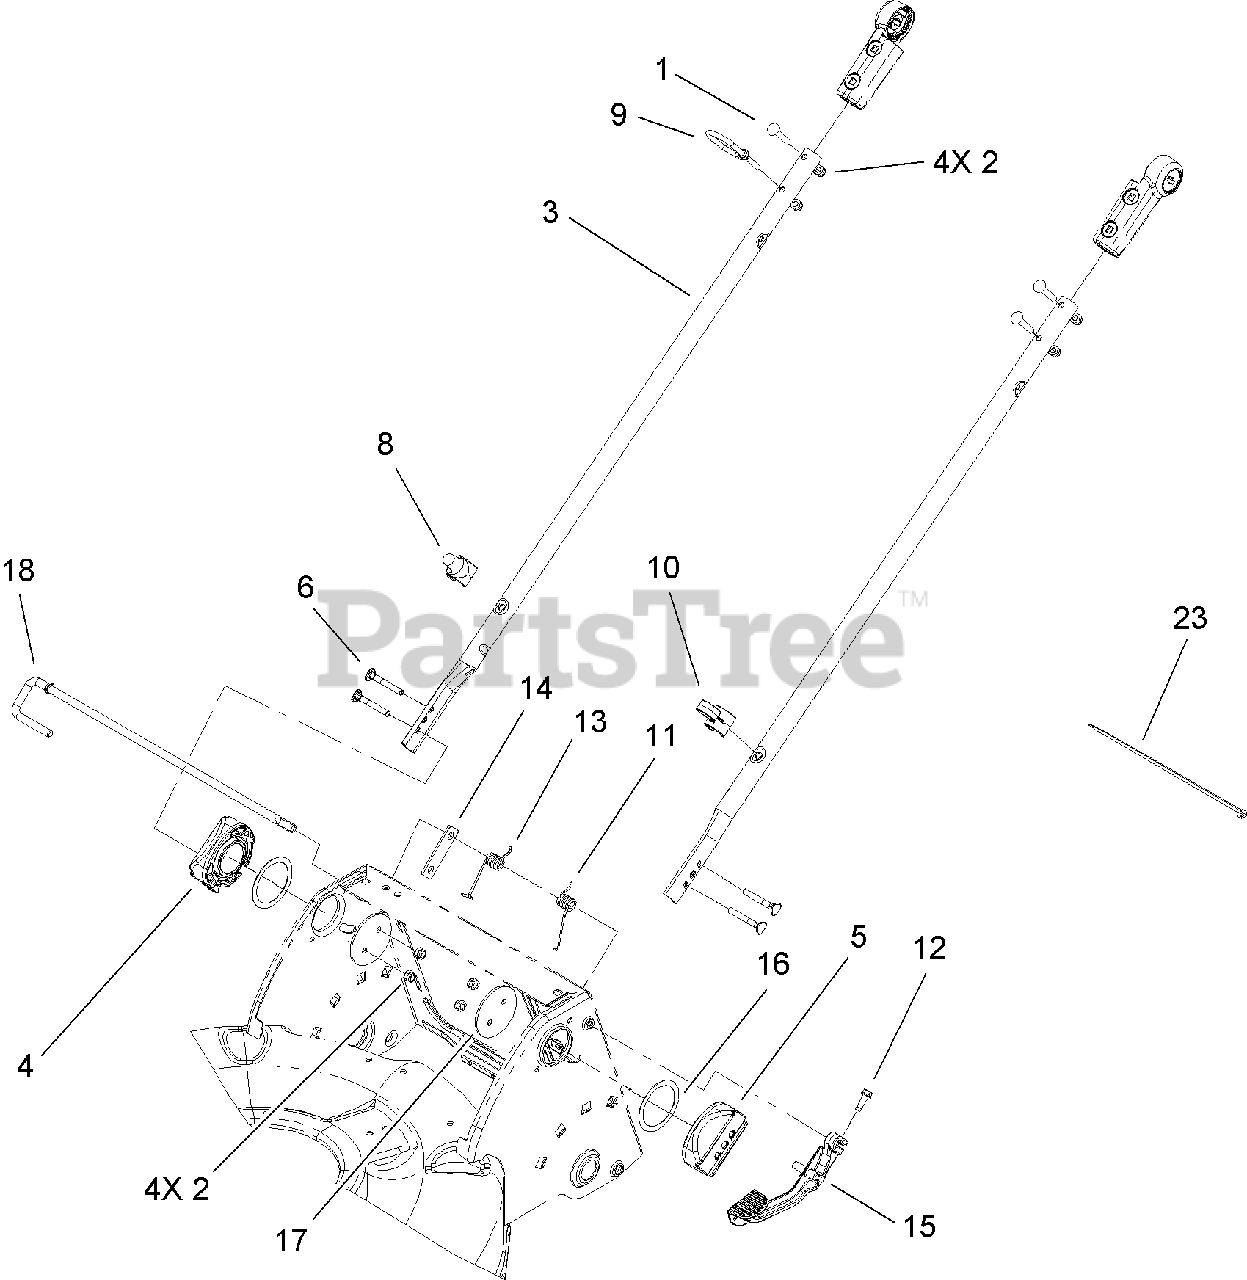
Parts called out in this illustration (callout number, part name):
1	SCREW-CARR
2	NUT-LOCK, NI
4	MOUNT-HANDLE, RH
5	MOUNT-HANDLE, LH
8	GUIDE-ROPE, LOWER
9	GUIDE-ROPE, UPPER
10	Guide-Cable
11	SPRING-TORSION, LH
12	SCREW-HWHTF
13	SPRING-TORSION, RH
14	PLATE-LOCK, HANDLE
15	LEVER-RELEASE
16	WASHER-NYLON
18	ROD-HANDLE RELEASE
23	STRAP-TIE
